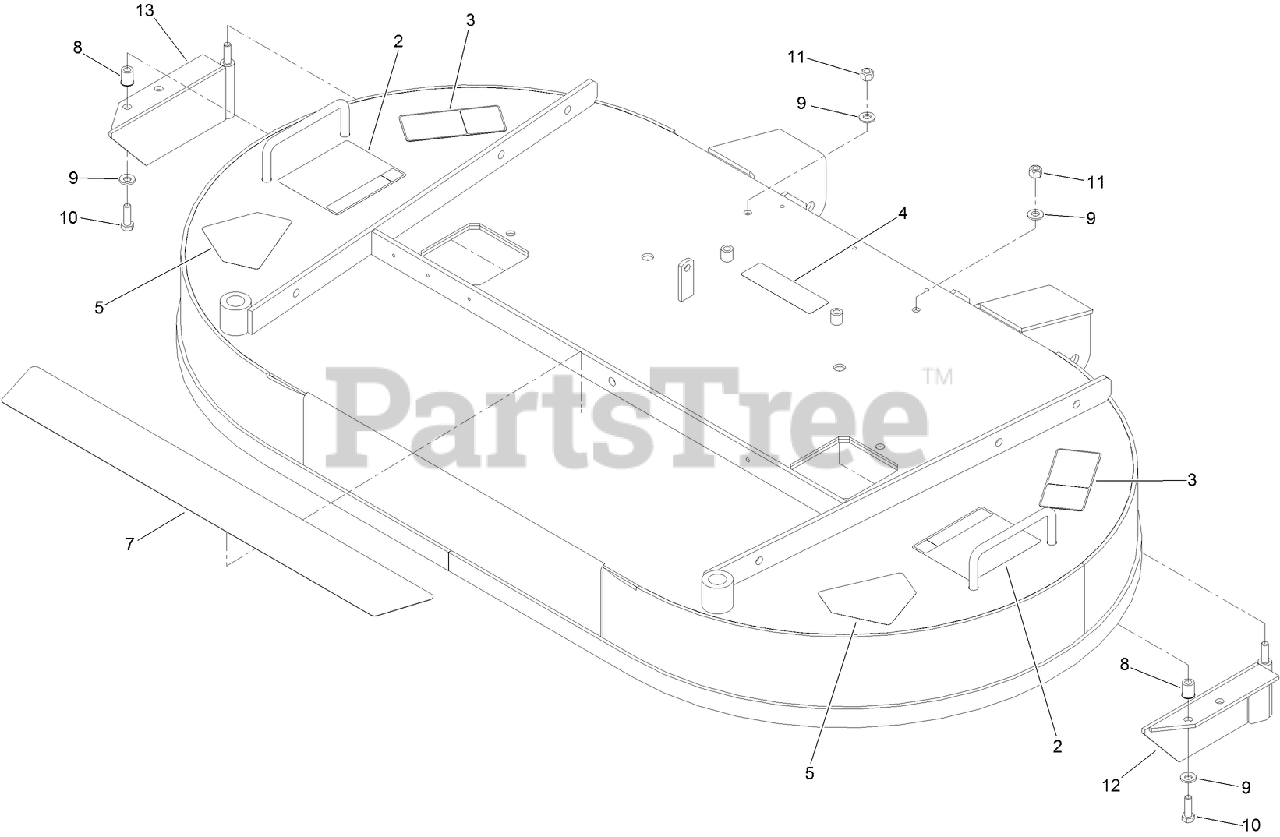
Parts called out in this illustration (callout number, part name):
2	DECAL-HEIGHT ADJUST, CUTTING
3	DECAL-TORQUE, BLADE BOLT
4	DECAL-MISSING, COVER
5	DECAL-DANGER
7	PAD-ANTI SKID
8	NUT-INSERT
9	WASHER-SPRING
10	SCREW-HH
11	NUT-LOCK, NI
12	BAFFLE-LH
13	BAFFLE-RH
